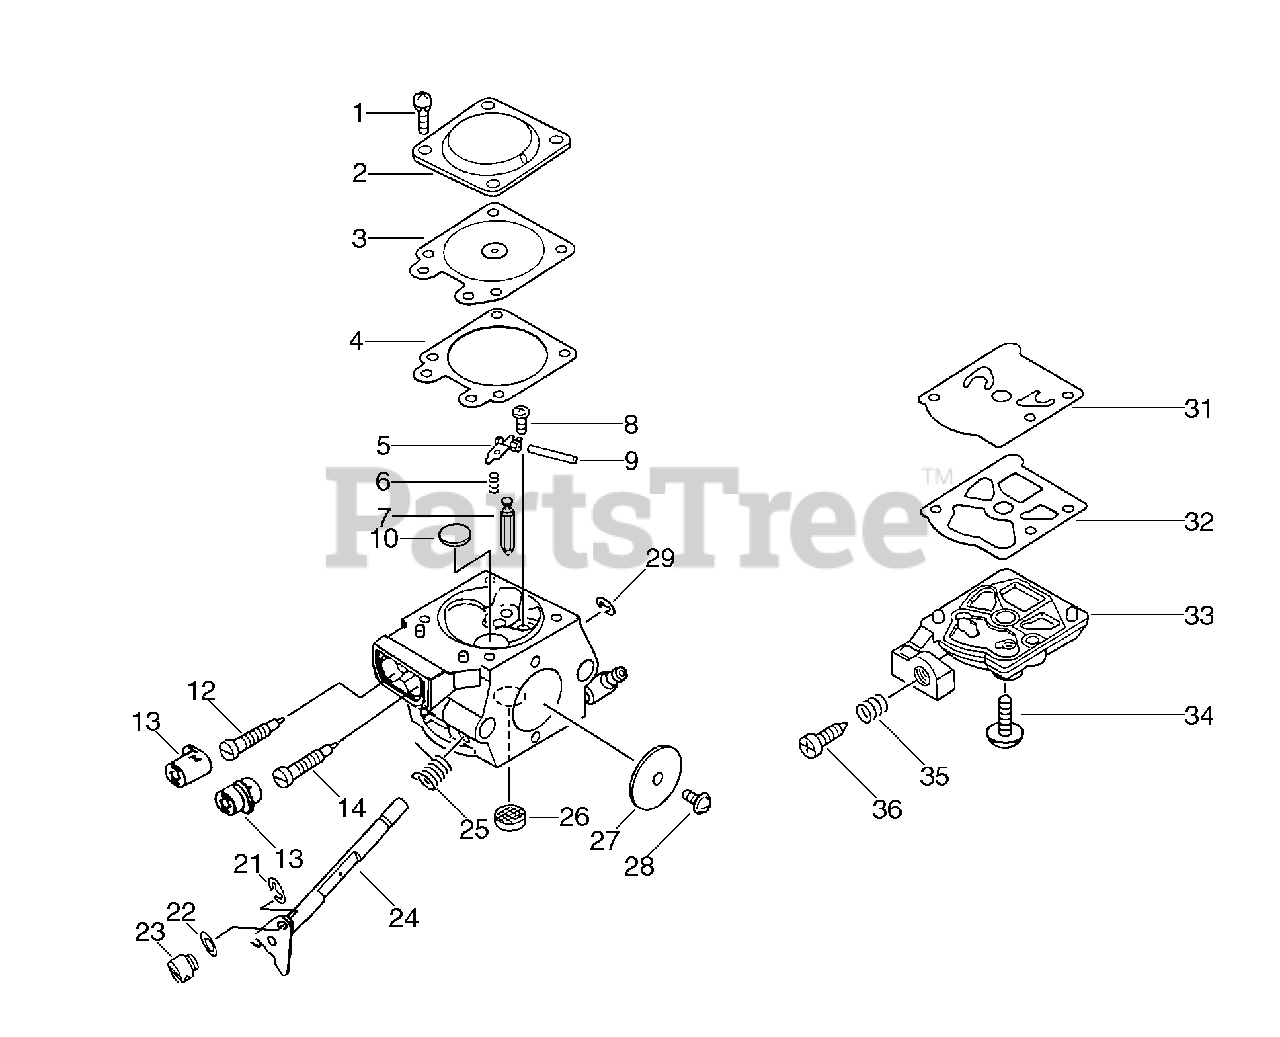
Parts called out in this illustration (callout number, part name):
2	COVER, METERING DIAPHRAGM
3	DIAPHRAGM, METERING
4	GASKET, METERING DIAPHRAGM
5	LEVER, METERING
6	SPRING, METERING LEVER
7	VALVE, INLET NEEDLE
8	SCREW, METERING LEVER PIN
9	PIN, METERING LEVER
10	PLUG, WELCH
12	NEEDLE, HIGH SPEED
13	CAP, LIMITER
14	NEEDLE, MIXTURE
24	SHAFT, THROTTLE
25	SPRING, THROTTLE RETURN
26	SCREEN, FUEL INLET
27	VALVE, THROTTLE
31	DIAPHRAGM, PUMP
32	GASKET, FUEL PUMP
33	COVER, FUEL PUMP
35	SPRING, IDLE ADJUST
36	SCREW, IDLE ADJUST
